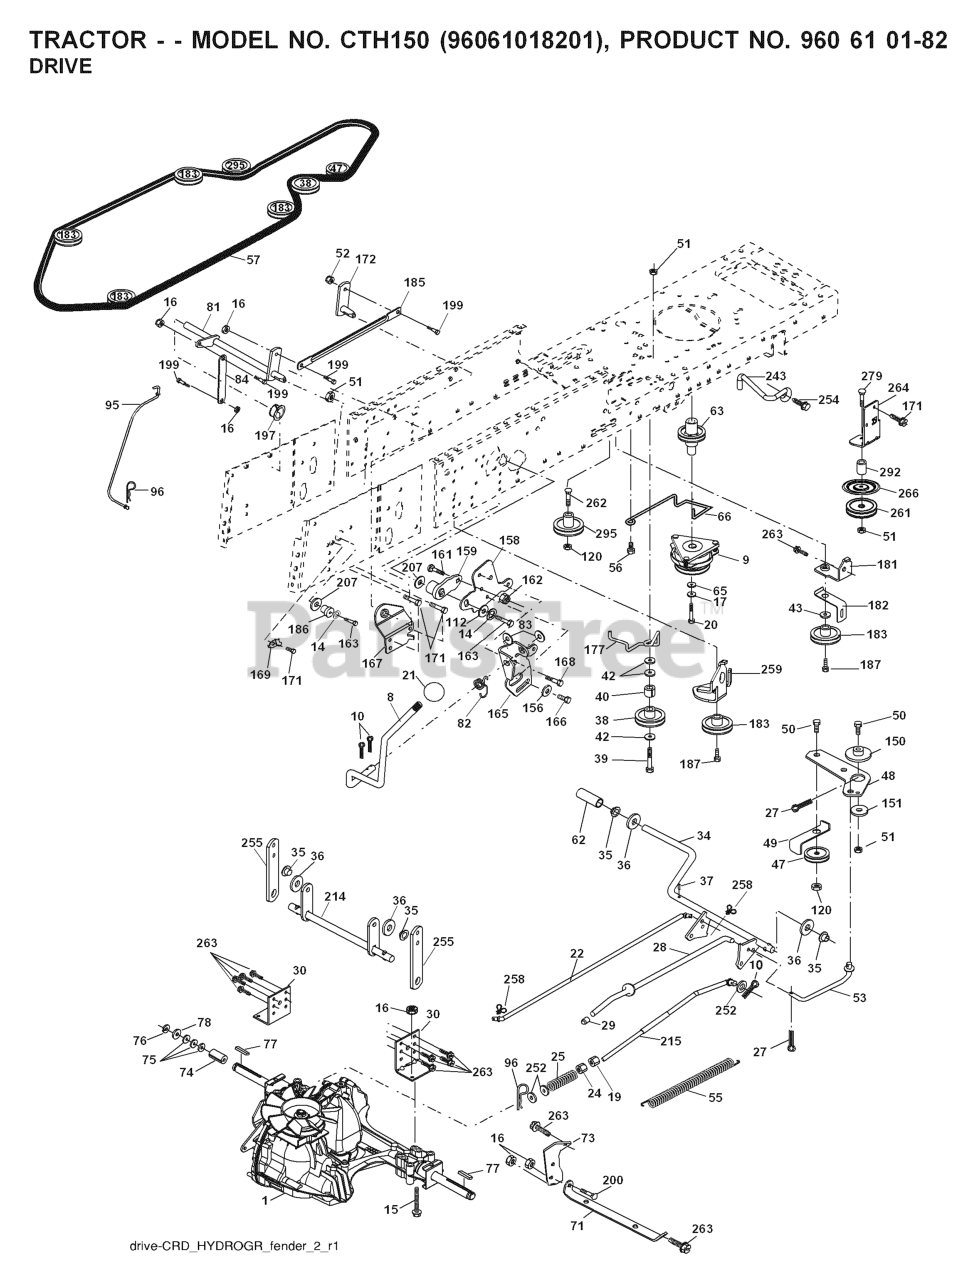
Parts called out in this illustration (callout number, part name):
8	ROD SHIFT FENDER ADJUST LT
10	PIN COTTER
14	LOCKWASHER
15	BOLT HEX 5/16-18 GR 5
16	NUT.71038.31-18.HEX.NYLOCK
19	NUT
20	BOLT HEX 7/16-20X4-1/4"
21	KNOB.DUCKHEAD.1/2
22	ROD
24	NUT
25	SPRING BRAKE ROD
27	COTTER PIN
28	ROD, PARKING BRAKE
29	CAP
30	BRKT, TRNSXLE MNT 20"
34	SHAFT, FOOT PEDAL
35	BEARING.NYLON
37	DRIVE PIN
38	PULLEY.FLAT
42	WASHER
47	IDLER PULLEY
48	BELLCRANK, CLUTCH
49	RETAIN BELT
50	BOLT.3/8-16X1.50
52	LOCKNUT
53	LINK.CLUTCH.7.66.2005
55	SPRING, RETURN LT
56	SCREW.3/8-16
57	V-BELT 113"
62	PEDAL COVER T
63	PULLEY.ENGINE.CVX.LT
65	LOCKWASHER
66	KEEPER BELT ENGINE
71	STRAP TORQUE LH HYDRO
73	STRAP TORQUE RH HYDRO
74	SPACER AXLE
77	SQUARE KEY
81	ASM.CROSS.SHAFT.REAR.CRD.0510
82	SHIFT SPRING
83	WASHER
84	LINK.PNT.TRANSAXLE.0510.CRD
95	LINK
96	RETAINER M
120	NUT LOCK FLG 3/8-16 UNC
150	BUSHING.BELLCRANK.GRD.DR
151	WASHER 12/32X2X10GA
156	WASHER.SRRTD.5/16
158	BRACKET
159	RB HUB.SHIFT
161	BOLT
162	NUT.CROWNLOCK.1/4
165	RP BRACKET
166	CAPSCREW.HXHD.FLG.5/16-18X.625
167	BRACKET.SUPT.SHIFT.CRD
168	BOLT.SHOULDER.5/16-18X
169	PLATE.FASTENING.CROSS.SHAFT
172	LINK
181	BRACKET
182	BELT GUIDE
183	PULLEY.V-IDLER.GRND.DR
185	LINK
186	HUB.TAPERED.ROUND.CRD
187	BOLT.5/16-18X1.25
197	NYLINER SNAP 5/8" ID
199	BOLT SHOULDER 5/16-18 UNC
207	WASHER NYL
214	LEVER
215	ROD
243	BRACKET, ANTI-ROTATION
252	WASHER
254	SCREW 3/8-16X1
255	SHAFT
258	CLIP RETAINER
259	BRACKET
261	FLAT IDLER PULLEY
263	SCREW, 3/8-16X3/4
266	PROTECTOR
292	SPACER
295	PULLEY IDLER COMPOSITE
